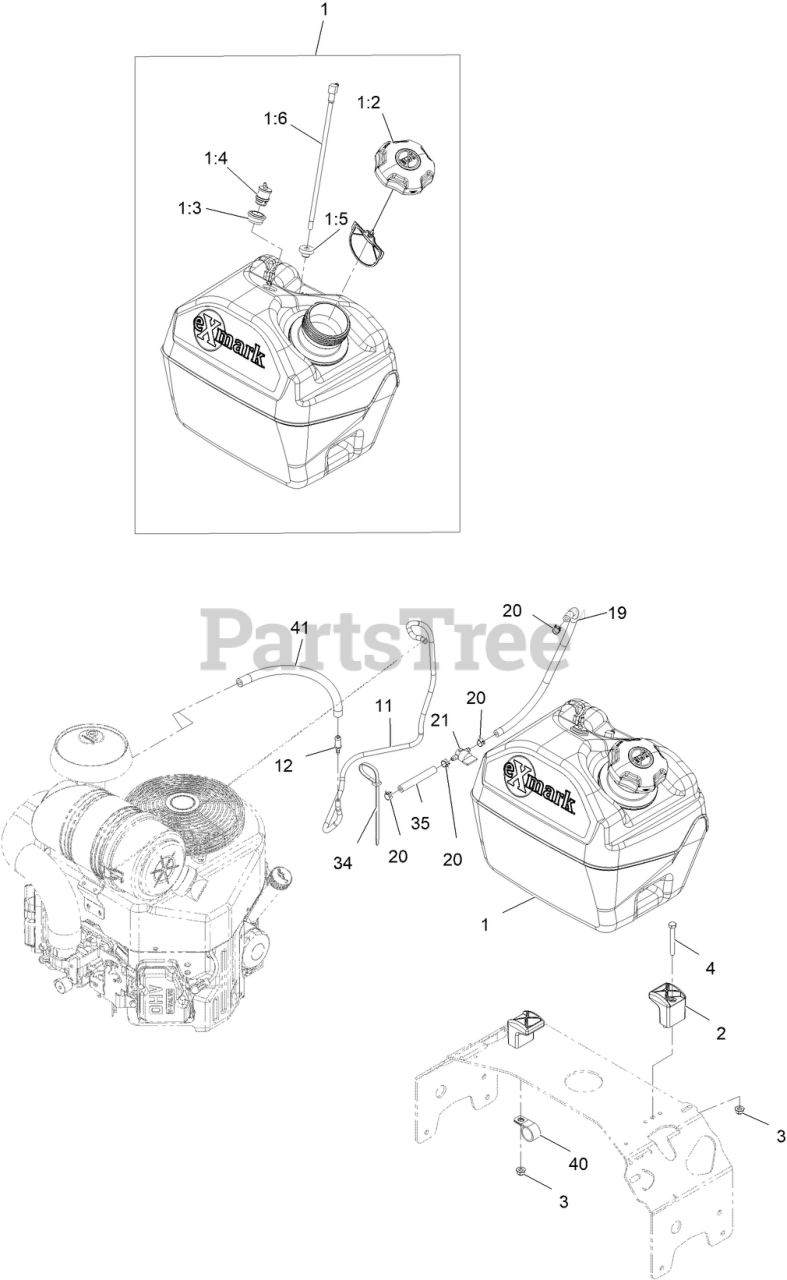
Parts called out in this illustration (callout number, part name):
1	ASM-Fuel Tank, 5 Gal, Exmark
1:2	CAP-FUEL, RATCHETING
1:3	GROMMET
1:4	VALVE-VENT, FUEL
1:5	BUSHING
1:6	FITTING, FUEL W/LINE AND SCREEN
2	CLAMP-TANK
3	NUT-HF, NI
4	SCREW-HH
11	HOSE, EMISSIONS
12	FITTING-STRAIGHT
19	HOSE-FUEL
20	CLAMP-HOSE
21	VALVE-FUEL
34	TIE-CABLE
35	HOSE-FUEL
40	CLIP-LOOM
41	HOSE-FUEL
